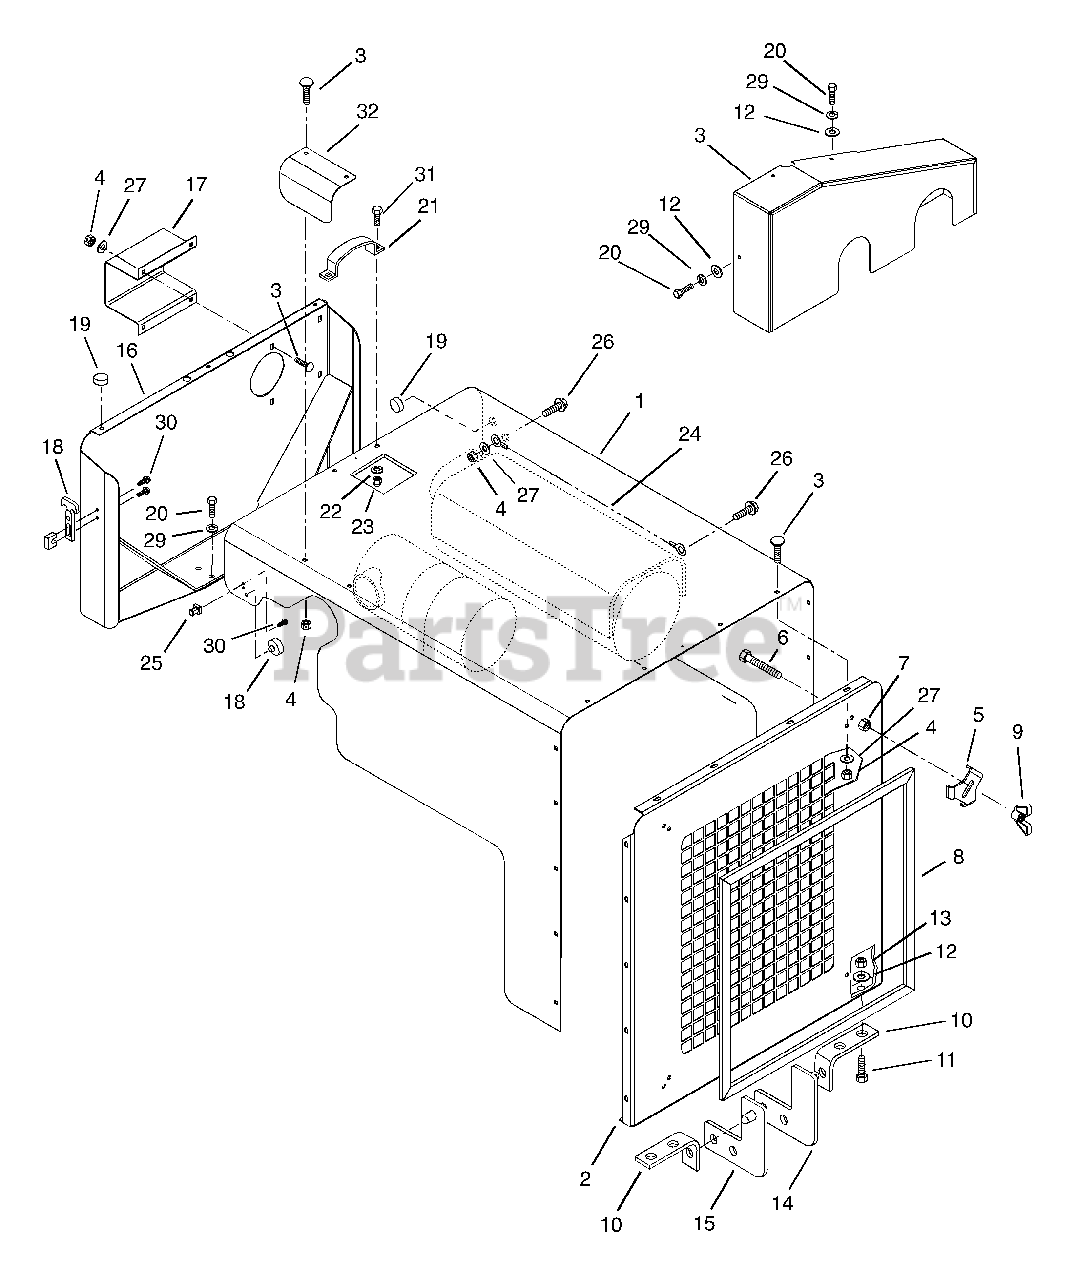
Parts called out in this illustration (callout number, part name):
1	Cowling-Top
2	Cowling-Front Weldment
3	Bolt-Round Head Square Neck .25-20 x .50 Grade 5
4	Nut-Locking-Center .25-20
5	Clip-Screen
6	Bolt-Hex .31-18 x 1.25 Grade 5
7	Nut-Locking-Center .31-18
8	Screen-Radiator 18 x 22
9	Nut-Nylock-Wing .31-18
10	Bracket-Cowling Mount
11	Bolt-Hex .38-16 x 1.00 Grade 5
12	Washer-Flat-Steel .438 x 1.00 x .083
13	Nut-Locking-Center .38-16
14	Left Pivot Weldment
15	Right Pivot Weldment
16	Cowling-Rear Weldment
17	Guard-Tail Pipe
18	Hook-Rubber
19	Button Bumper
20	Bolt-Hex .38-16 x .75 Grade 5
21	Handle-Cowling
22	Washer-Locking .31 x .078
23	Nut-Crown .31-18
24	Cable
25	Bolt-Hex M8 1.25 x 16 mm
26	Bolt-Hex .25-20 x .75 Grade 5
27	Washer-Flat-Steel .312 x .734 x .065
28	Guard-Belt Weldment
29	Washer-Locking .38 x .094
30	Screw-Machine-Hex Washer Head 10-24 x .75
31	Bolt-Hex .31-18 x .75 Grade 5
32	Guard-Air Cleaner Inlet
